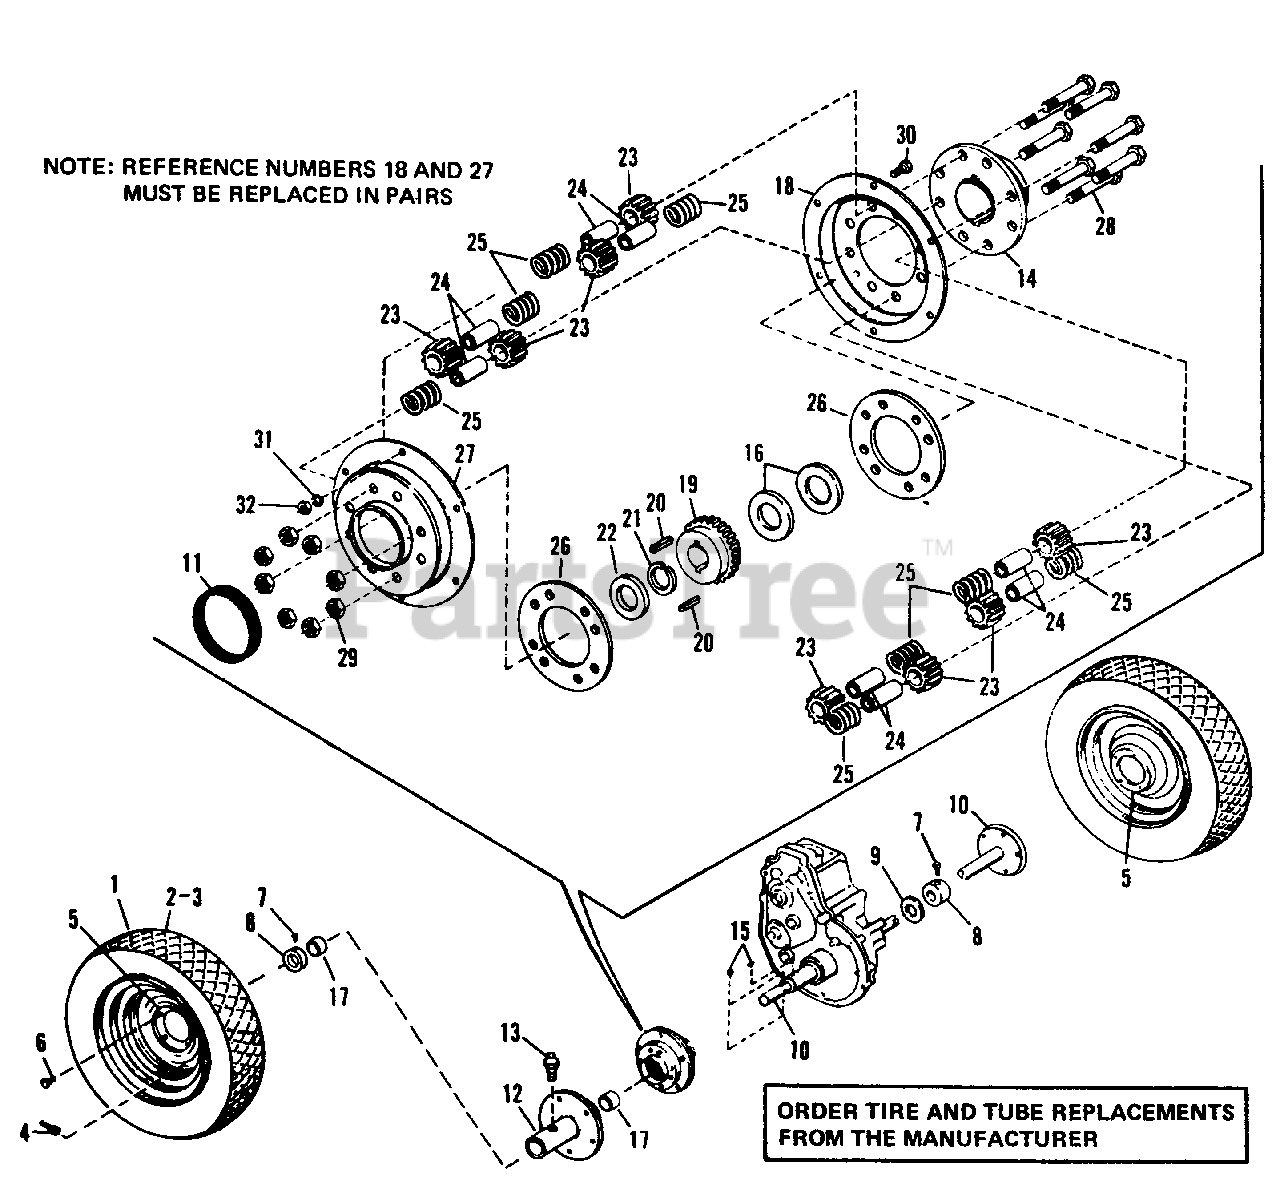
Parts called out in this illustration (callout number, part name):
1	WHEEL & TIRE ASSEMBLY
4	STEM, Valve & Cap
5	WHEEL, Drive
7	SCREW, Set, 5/16"-18 x 3/8" lg.
8	COLLAR, Set
10	REAR AXLE ASSEMBLY
11	SEAL, Diff. Cover
12	HUB ASSEMBLY
13	FITTING, Grease
14	CARRIER, Diff.
16	WASHER, Axle
18	COVER, Diff.
19	GEAR, Diff.
21	RING, Retaining
22	WASHER, Axle
23	PINION, Diff.
24	SPINDLE, Pinion, Diff.
26	RING, Spacer
27	COVER, Diff.
28	CAPSCREW, Hex, 3/8"-18 x 2-1/2" lg.
29	NUT, Hex, Full, Lock, 3/8"-16
30	CAPSCREW, Hex, 1/4"-20 x 5/8" lg.
31	LOCKWASHER, 1/4"
32	NUT, Hex, Full, 1/4"-20
